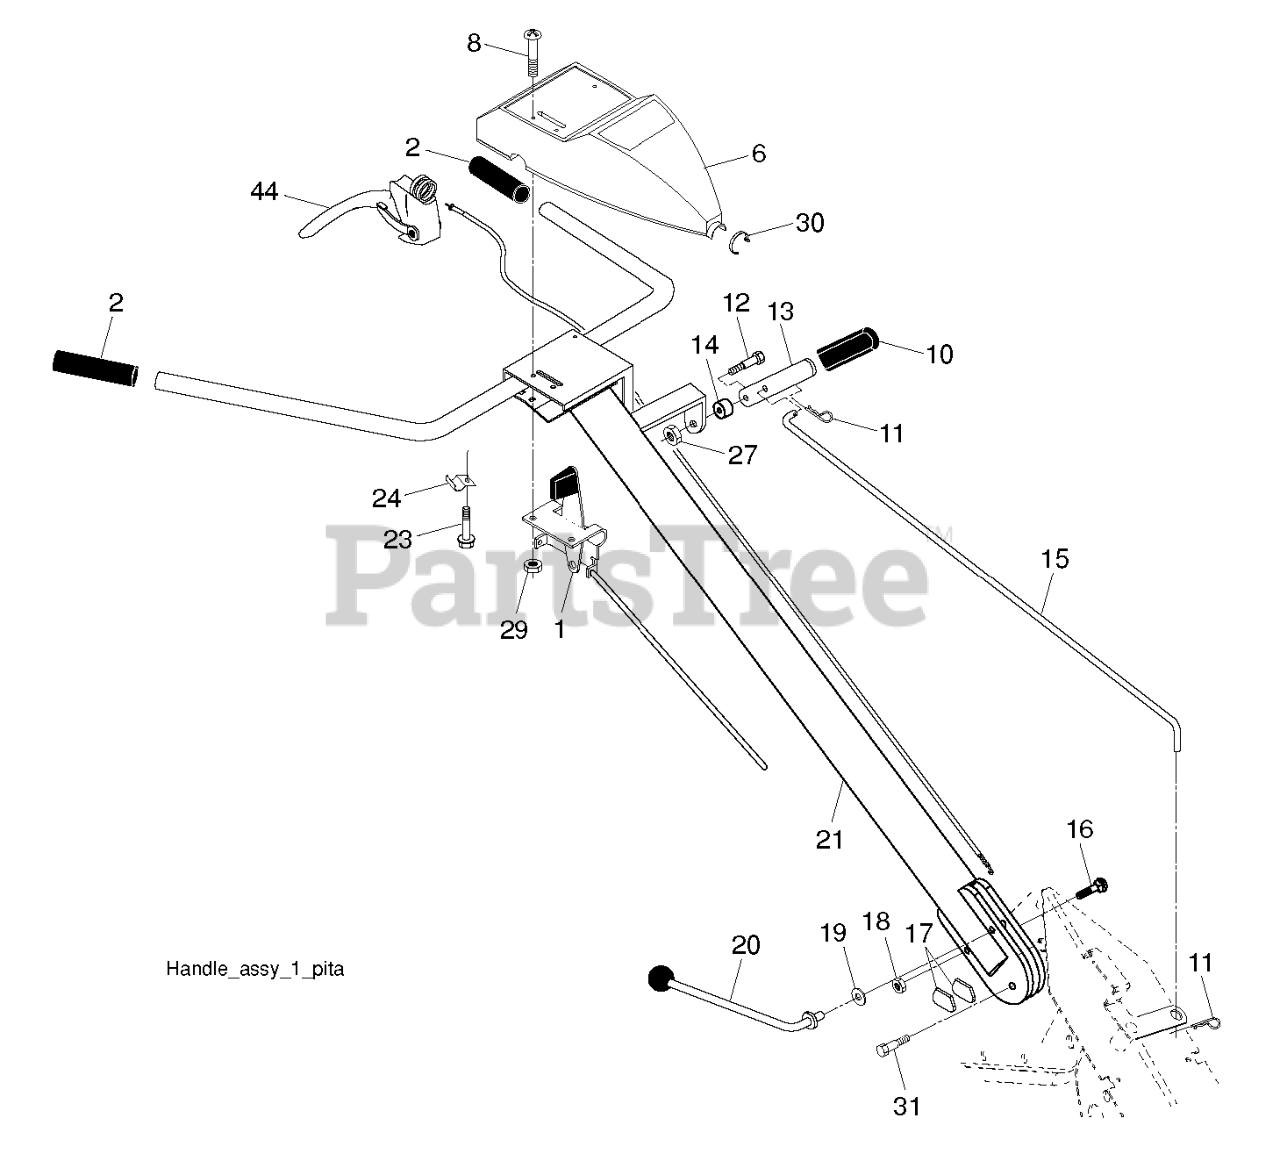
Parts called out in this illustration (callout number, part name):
1	RP.CONTROL.THROTTLE.47.W/Z.BEN
2	GRIP.1X5.06
6	PANEL.CONTROL.ORANGE.MS668
8	SCREW.PNHD.10-24
11	RETAINER M
12	SHOULDER BOLT ST
13	HANDLE
14	GROMMET.RUBBER.CRT.TILLER
15	ROD.SHIFT.YARD PRO.UNIVERSAL.
16	BOLT D
17	LOCK.HANDLE.CRT
19	WASHER CRT
20	LEVER.LOCK.CRT
21	HANDLE.ASM.TILLER.GREY.
23	TAPPING SCREW
24	CONDUIT.CLIP.PLATED
27	NUT T
29	NUT **
30	TIE CABLE CRT
31	BOLT.PIVOT
44	CONTROL.HANDLE.TWO.FUNCTION.CE
